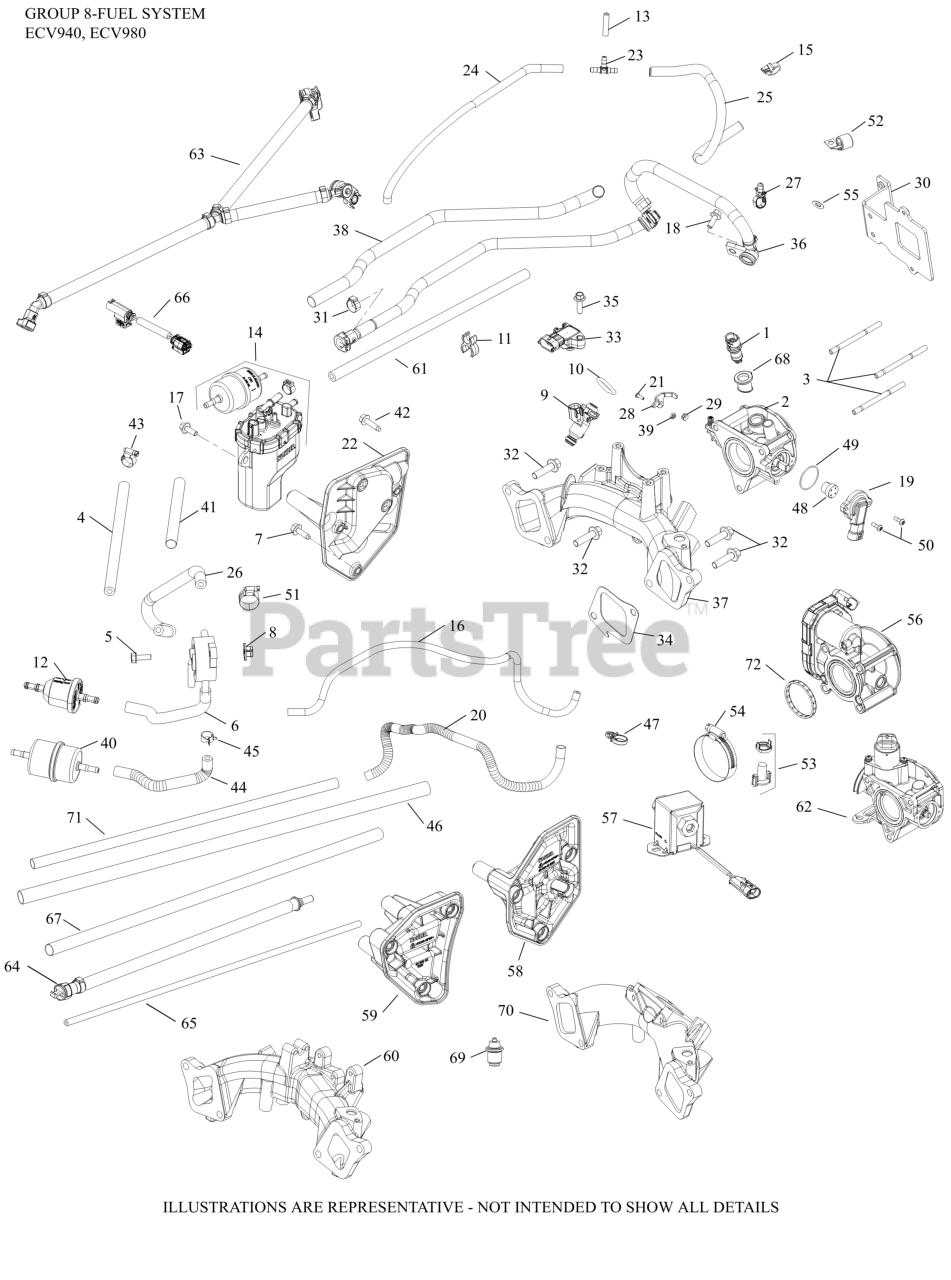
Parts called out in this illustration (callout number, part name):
1	SENSOR, AIR TEMPERATURE
2	KIT, THROTTLE BODY ASSEMBLY
3	STUD,M6X1.0X84
4	LINE, FLEXIBLE FUEL
5	SCREW, TAP M6X1.7X18
6	PUMP, FUEL
7	SCREW, THREAD FORMING
8	NUT, PLASTIC - BLACK
9	INJECTOR, FUEL
10	KIT, FUEL INJECTOR O-RING
11	RETAINER, CLIP
13	CAP, MASKING
14	KIT,FP MODULE (ECH/ECV 440,630,940)
16	HOSE, EVAPORATIVE 20"- (#24326143S)
17	SCREW, FLG M6X1.0X16
18	SCREW, FLG M6X1.0X16
19	SENSOR, THROTTLE POSITION
20	SLEEVE, ANTI-ABRASION
22	BAFFLE, V/S FUEL PUMP MODULE
23	TEE CONNECTOR
24	HOSE, EVAPORATIVE
25	SLEEVE, ANTI ABRASION
26	HOSE, FUEL LINE
30	BRACKET, ECU MOUNTING-USE 62 126 76-S
31	CLAMP, HOSE
31	CLAMP, OETIKER
32	SCREW, FLG M8X1.25X30
33	SENSOR, MAP
34	GASKET, INTAKE MANIFOLD
36	FUEL HOSE ASSY ECV940 THRU ECV980
37	MANIFOLD, INTAKE EFI - VERTICAL
38	SLEEVE, ANTI ABRASION
40	FILTER, FUEL
41	SLEEVE, ANTI ABRASION -USE 25 431 12-S
43	CLAMP, HOSE (KM)-USE 25 237 31-S
44	HOSE,LW PERM.FUEL 24.00"-USE 25 111 81-S
45	SPRING CLAMP, HOSE
46	SLEEVE, HEAT REFLECTIVE
51	CLAMP, HOSE-USE 25 237 32-S
54	CLAMP, HOSE-USE 25 237 21-S
